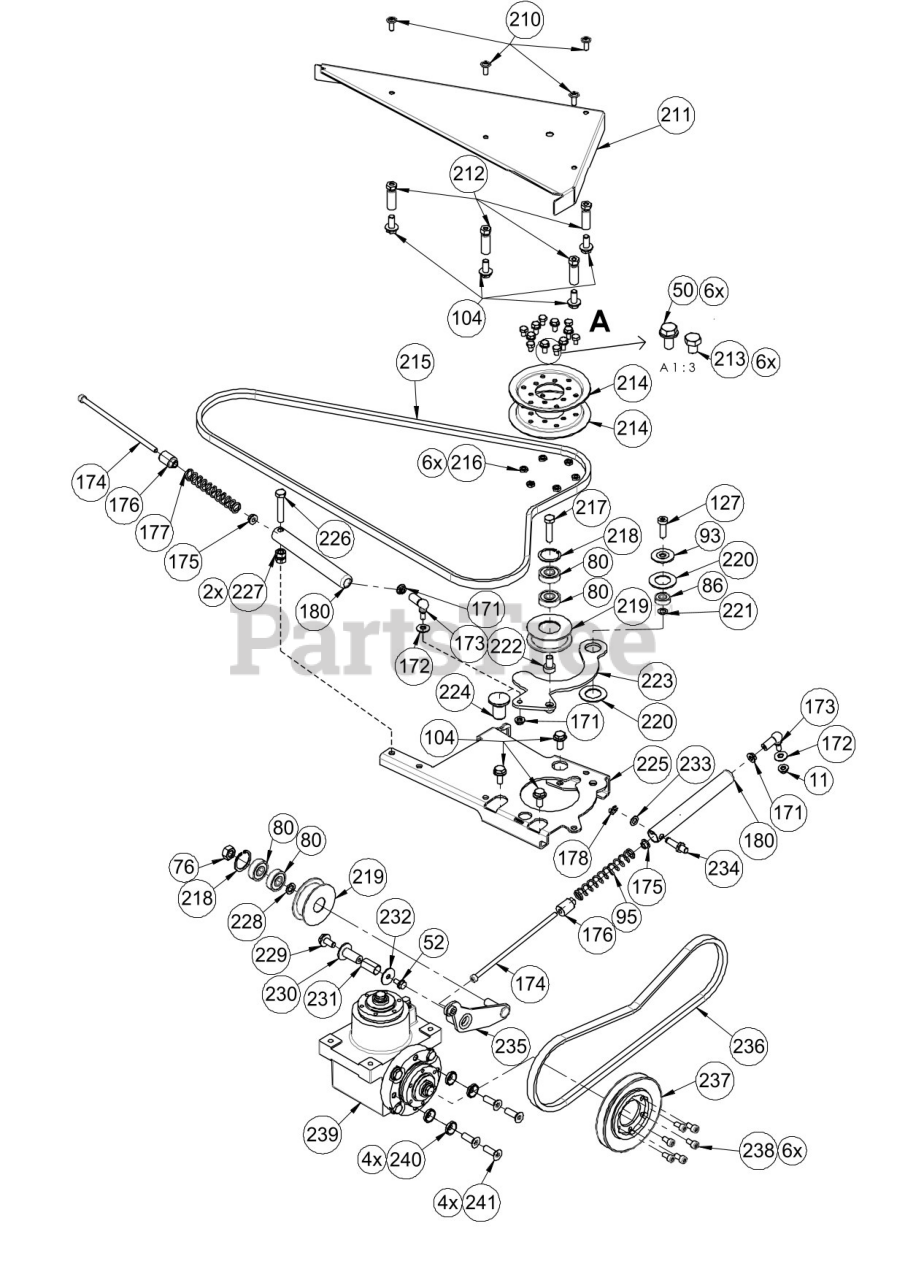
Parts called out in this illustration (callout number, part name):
11	NUT, FLG SLF LK M6 CL 8 ZCC
50	BLT, FLG SLF LK M6X12
52	BLT, FLG M6X12 DIN 6921 8.8 ZCC
76	NUT, HEX M10 DIN 934 8 ZCC
80	BRG,BALL 6200-2RSH (10X30X9)
86	BRG,BALL .608-2RS DIN625 (8X22X7)
93	WASHER, BEARING (STEPPED)
95	SPRING, COMPRESSION
104	BLT, SER FLG M8X18 VERBUS RIPP
127	TORX SHCS M8X25 SIMILAR TO DIN 7984 8.8
171	NUT, FLG M6 DIN 6923 8 ZCC
172	WSHR, LK EDGE F M6
173	JOINT, BALL
174	SCR, SKH M6X160 8.8 ZCC
175	BSHG, DU FLG BB 061006
176	GUIDE, COMP. SPRING
177	SPRING, COMPRESSION
178	RETAINER, KL 8 MBO 09
180	SLEEVE, SPRING
210	TORX FBHCS M6X16-8.8
211	COVER, BELT
212	GUIDE, BELT
213	BLT, HEX M6X8 DIN 933 8.8 ZCC
214	HALF, PULLEY (FINAL DRIVE)
215	V-BELT, DRIVE - FINAL
216	NUT, JAM B M6 DIN 439 ZCC
217	BLT, HEX M8X35 DIN 931 8.8 ZCC
218	RG, RTNG-INT 30X1.2 DIN 472
219	PULLEY, IDLER
220	WSHR, FLT M22 X M38 X M1.5
221	WSHR, FLT M8 X M14 X M.5 DIN 988
222	SPACER, FLANGED
223	ARM, IDLER (FINAL DRIVE)
224	STOP, IDLER ARM
225	BRACKET, GEARBOX MOUNT
226	BLT, HEX M8X 45 DIN 931 8.8 ZCC
227	NUT, HEX M8-1.25 G8.8 ZCC
228	WSHR, FLT M10XM16XM2
229	BLT, SER FLG M8X16
230	BUSHING, IDLER ARM
231	BSHG, DU SLV MB 1225 DU
232	WSHR, FLT M6.4XM25X1.5
233	WSHR, FLT M8 X M14 X M1 DIN 988
234	FOLLOWER, SHORT
235	ARM, IDLER (PRIMARY DRIVE)
236	V-BELT, DRIVE - PRIMARY
237	PULLEY, PRIMARY DRIVE
238	SCR, SKH M6X12 DIN ISO 4762 8.8
239	GEARBOX, ANGLE
240	WASHER, CONE
241	TORX FHCS M8X25 8.8
